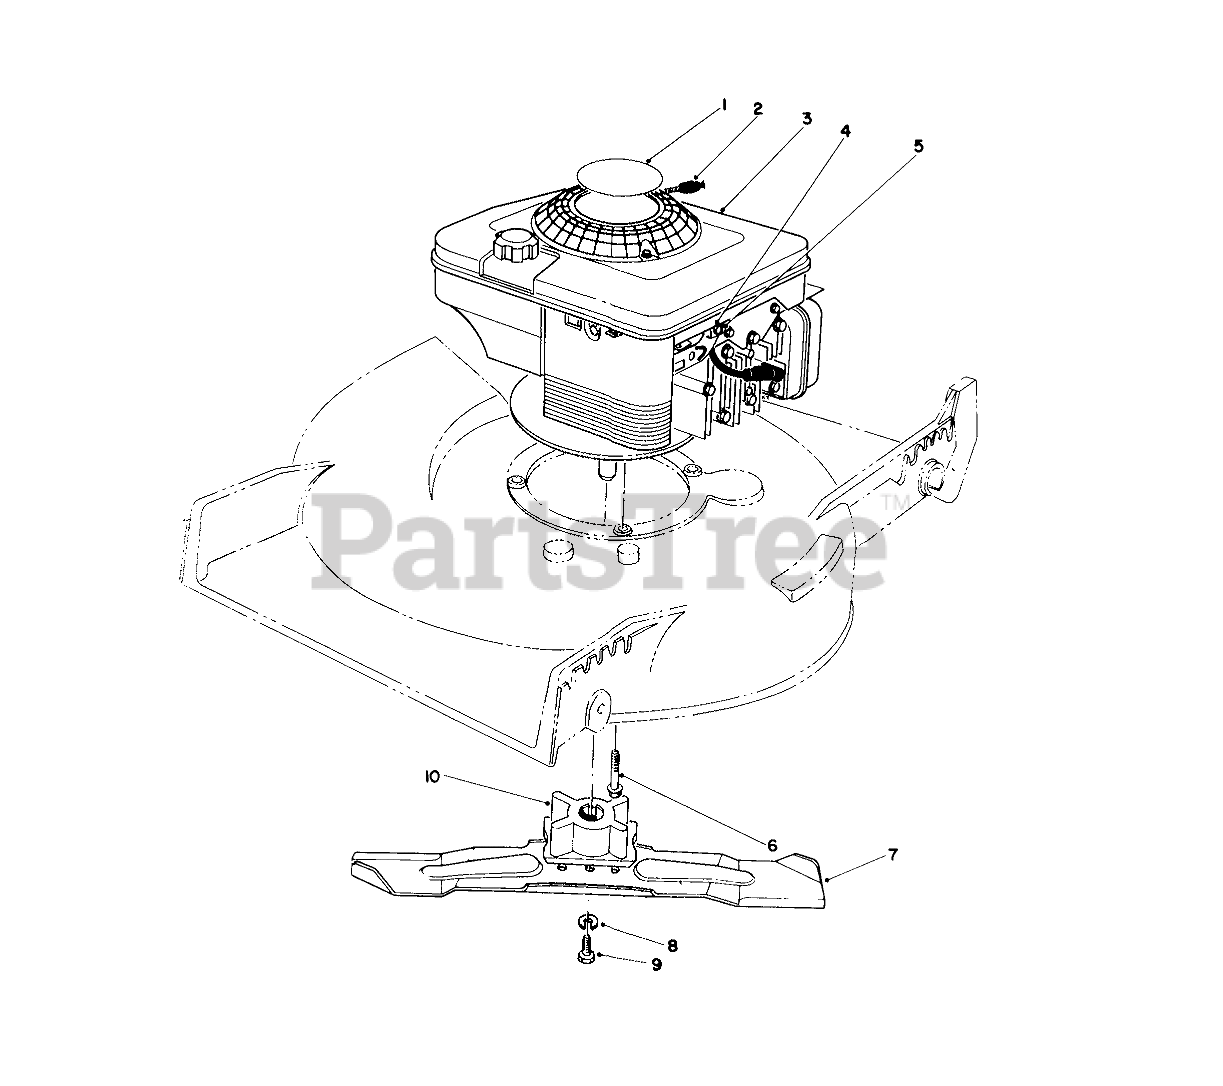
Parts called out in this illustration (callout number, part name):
1	DECAL - ENGINE
2	STOP-ROPE
4	CLAMP-CASING
5	Screw
6	SCREW-HWH
7	BLADE-21in
8	WASHER-LOCK
9	SCREW-BLADE
10	BLADE RETAINER
